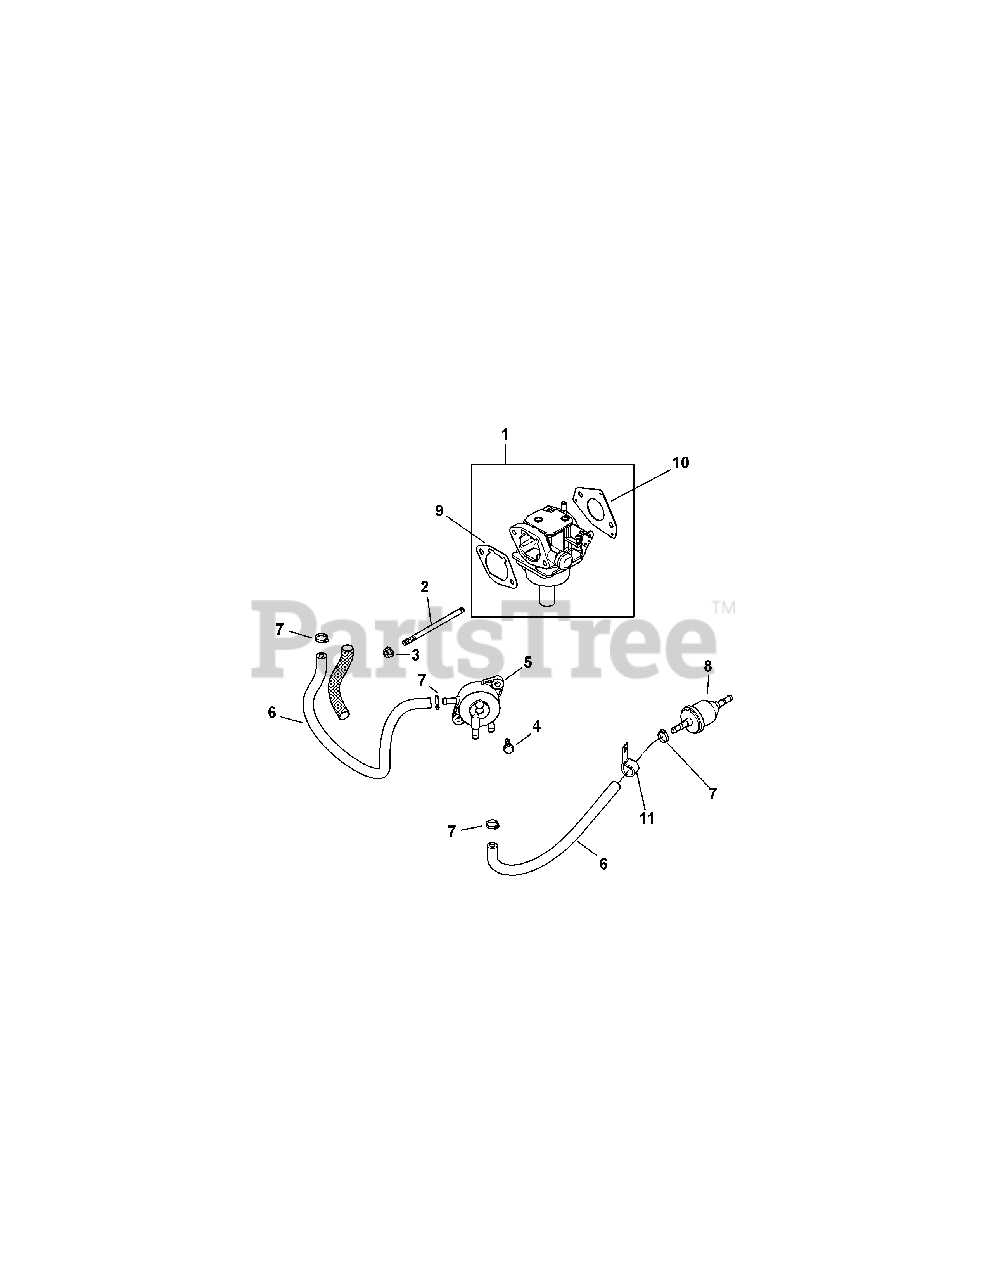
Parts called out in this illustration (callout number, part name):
1	Carburetor Kit
2	Stud, M6 x 1.0 x 106
3	Flange Nut, M6 x 1.0
4	Tap Screw, M6 x 1.7 x 18
6	Fuel Line
7	Hose Clamp, 1/2
9	Air Cleaner Base Gasket
10	Carburetor Gasket
